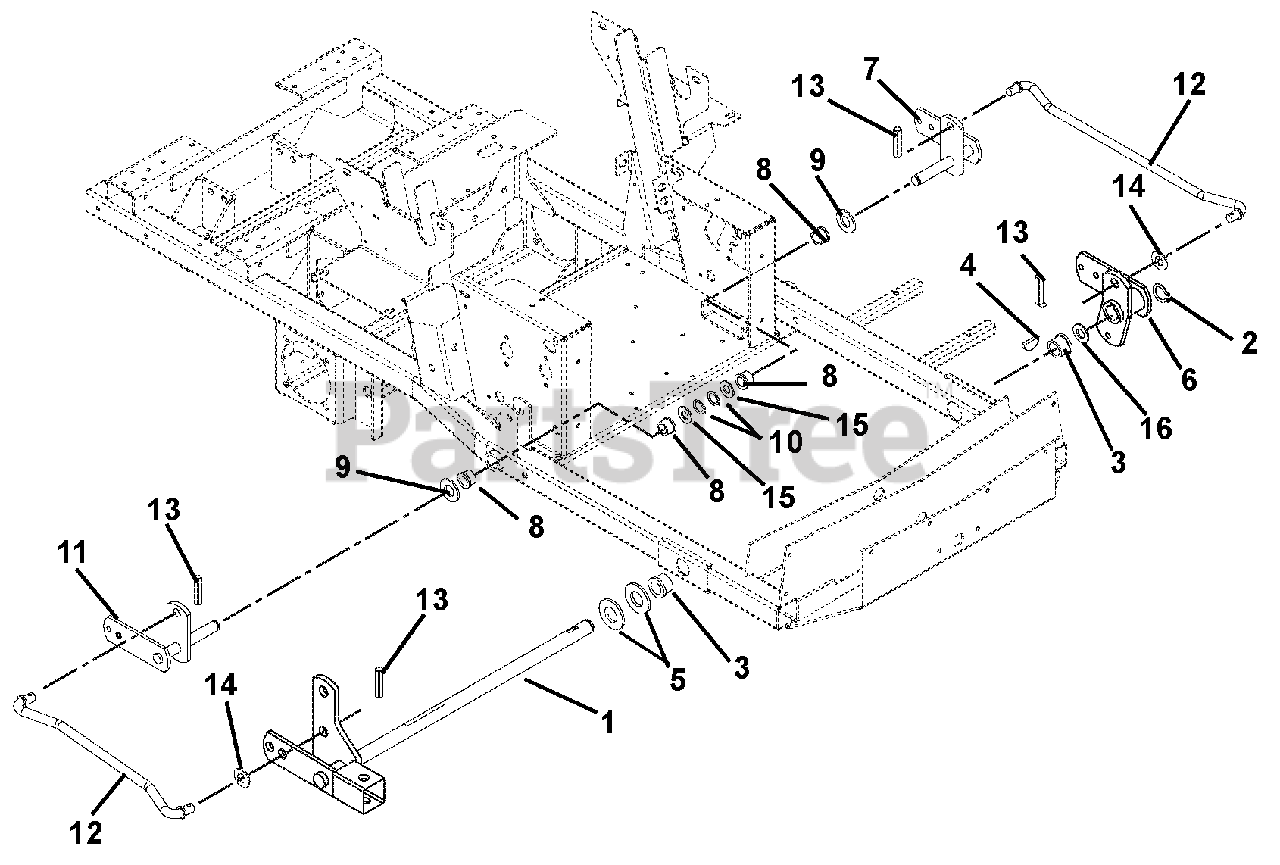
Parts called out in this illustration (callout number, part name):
1	MOWER LIFT
2	RG-RTNG-EXT 1.00X.078
3	BSHG-FLG1.020X1.385X.75X1.75NY
4	KEY-WDRF .25X1.00 HRD #15
5	WSHR-FL-STL 1.063X2.00X.134
6	WMT, FRONT MOWER LIFT-LH
7	WMT, REAR LIFT ARM -LH
8	BSHG-FLG .762X1.0X.580X1.48 NY
9	WSHR-HDND-THRST .758X1.23X.031
10	RG-RTNG-EXT .689X.078
11	WMT, REAR LIFT ARM - RH
12	ROD, LIFT ASSIST 19.35"
13	PIN-ROLL .250X1.25 STNLESS STL
14	WSHR-FL-STL .630X1.250X.062 YZ
15	WSHR-FL-STL .755X1.25X.125 YZ
16	WSHR-HDND-THRUST 1.00X1.55X.03
